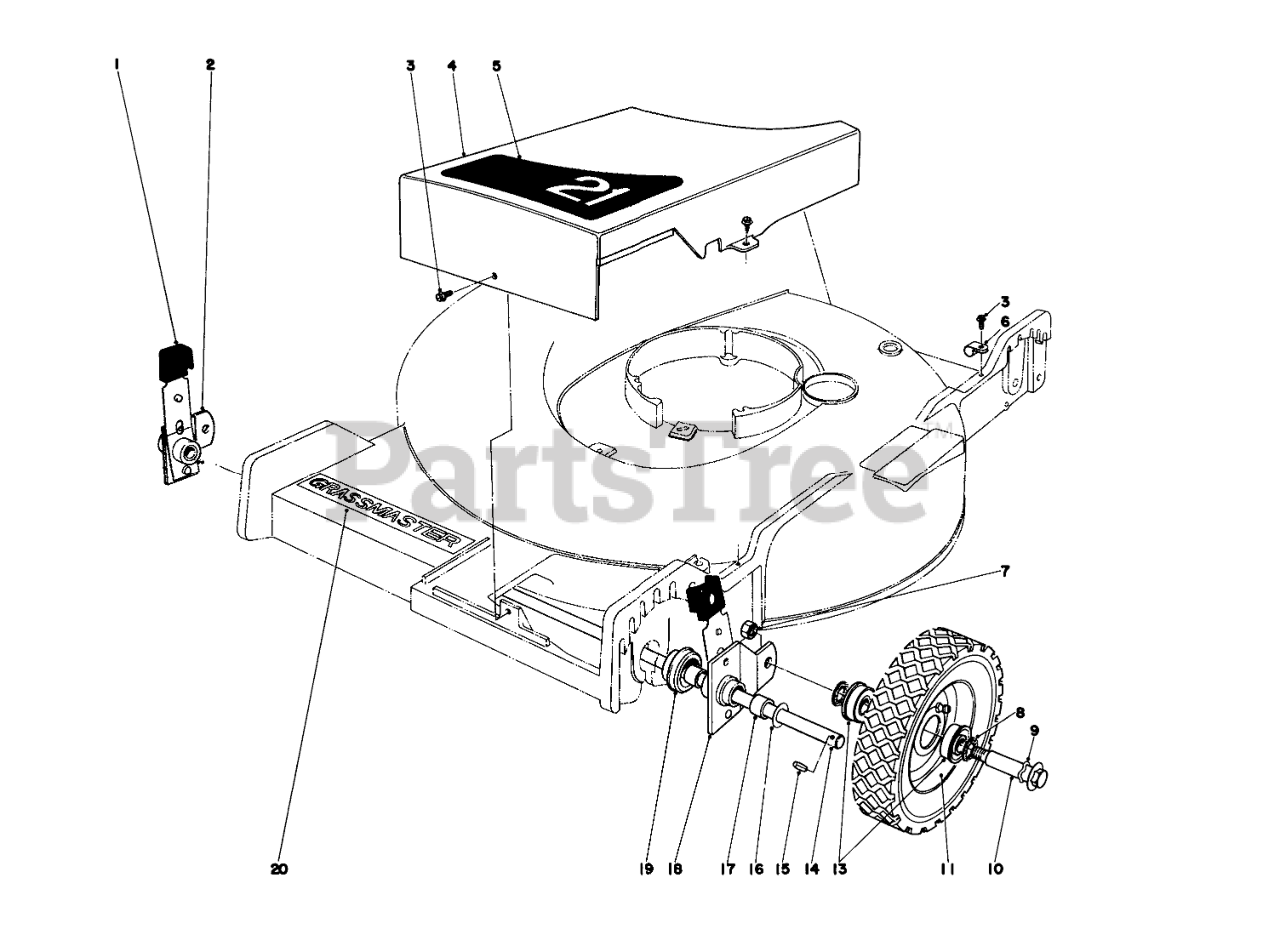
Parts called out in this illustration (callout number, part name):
1	KNOB-ARM
2	Pivot Arm (Incl. Ref. #17)
3	SCREW
4	Belt Cover
5	Decal
6	CABLE CLAMP
7	Nut
8	FELT WASHER
9	SPRING WASHER
11	Wheel & Tire assembly (Incl. Ref. #13)
13	BEARING-BALL
14	Shaft-Pivot Arm
15	PIN-GROOVED
16	WASHER-THRUST
17	BUSHING
18	Pivot Arm (Incl. Ref. #17)
19	End Cap
20	Decal Grassmaster
